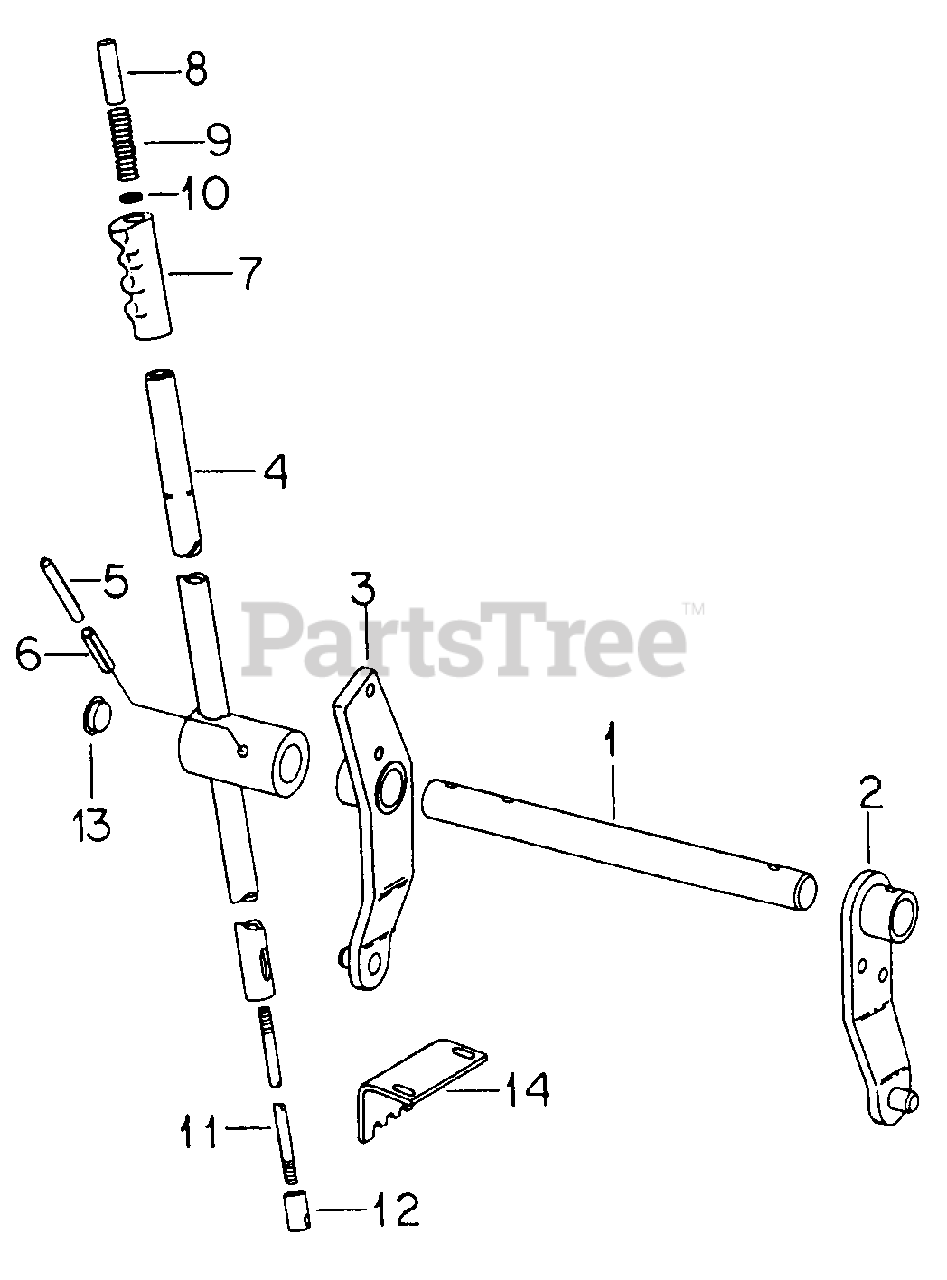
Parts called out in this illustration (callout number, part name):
1	Rockshaft
2	Arm Assy, Lift, LH
3	Arm Assy, Lift, RH
4	Handle Assy, Lift
5	Pointer, Lift
6	Pin, 3/8 X 2 Hvy Pln Cld Spr
7	Grip, Lift Handle
8	Plunger, Release
9	Spring, Lift Handle
11	Stud, Handle
12	Rod, Handle Release
13	Plug, Button
